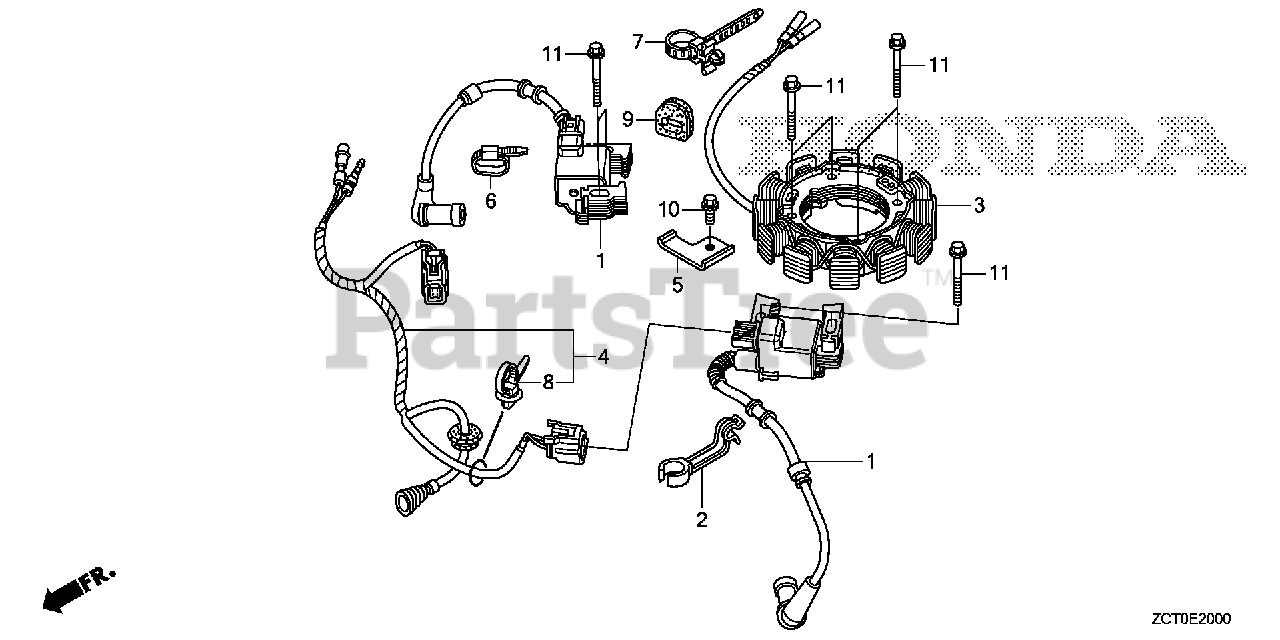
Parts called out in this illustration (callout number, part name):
1	COIL ASSY., IGNITION
2	CLAMP, IGNITION WIRE
3	COIL ASSY., CHARGE (26A)
4	WIRE HARNESS ASSY., ENGINE
5	BRACKET, HARNESS
6	BAND, WIRE (95MM)
7	STRAP, CABLE (105MM) (BLACK)
8	CLIP, HARNESS BAND (145MM) (BLACK)
9	GROMMET, CORD
10	BOLT, FLANGE (6X12)
11	BOLT, FLANGE (6X32)
